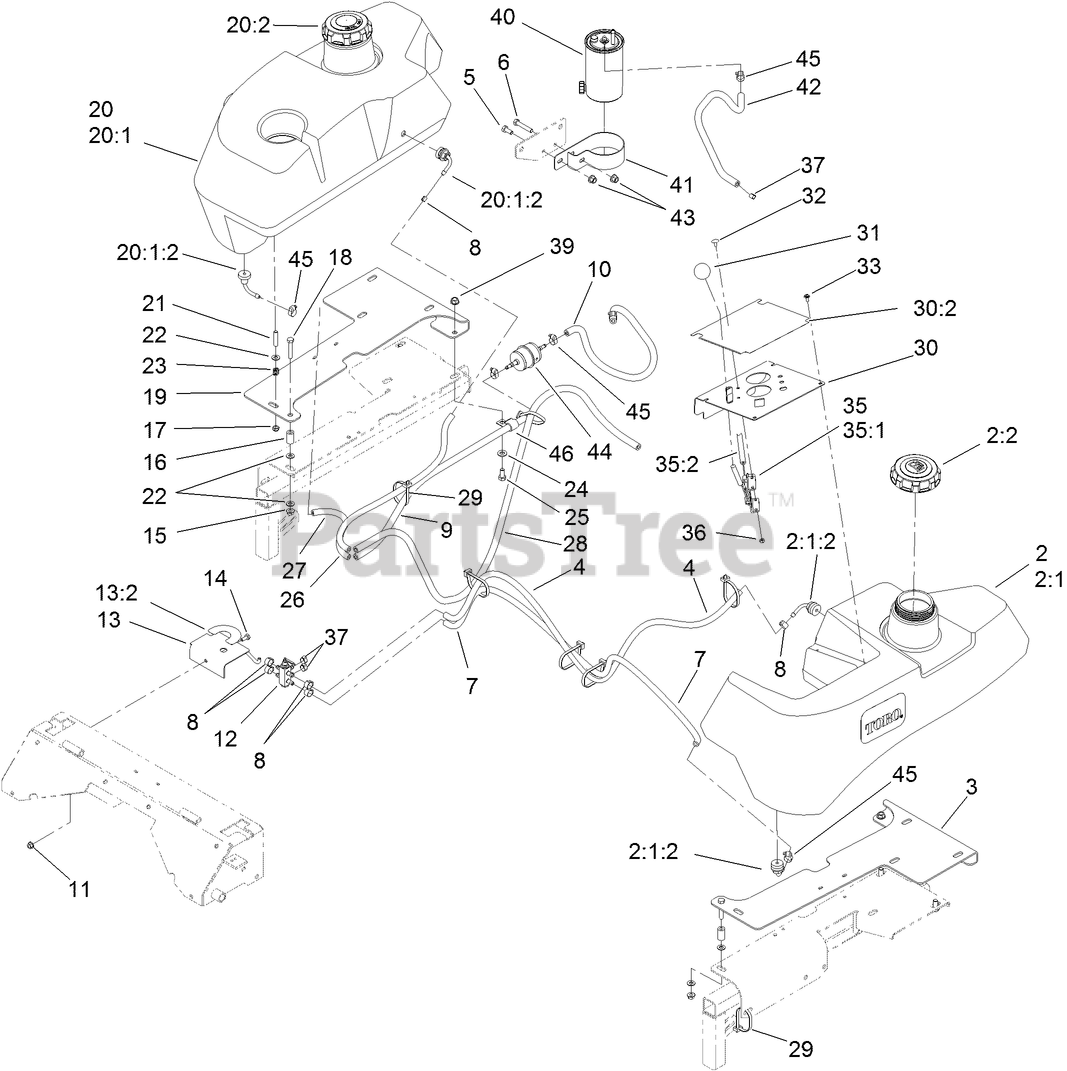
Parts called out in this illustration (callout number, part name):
2	LH FUEL TANK KIT
2:1	Tank-Fuel, LH
2:1:2	FITTING-FUEL, BULKHEAD
2:2	BIODIESEL CAP ASM
3	BRACKET-FUEL TANK, LH
4	HOSE-FUEL
5	SCREW-HH
6	SCREW-HH
7	HOSE-FUEL
8	CLAMP-HOSE, FUEL
9	HOSE-FUEL
10	HOSE-FUEL
11	NUT-HF
12	VALVE-FUEL, DUAL FLOW
13	BRACKET-VALVE, FUEL
13:2	DECAL-VALVE, FUEL
14	SCREW-HH
15	NUT-LOCK, NI
16	SPACER
17	NUT-LOCK, NI
18	SCREW-HH
19	BRACKET-FUEL TANK, RH
20	RH FUEL TANK KIT
20:1	Tank-Fuel, RH
20:1:2	FITTING-FUEL, BULKHEAD
20:2	BIODIESEL CAP ASM
22	WASHER-PLAIN
23	SPRING-TANK, FUEL
24	WASHER-FLAT
25	SCREW-HH
26	HOSE-FUEL
27	HOSE-FUEL
28	HOSE-FUEL
29	TIE-PLASTIC
30	CONTROL PANEL ASM
30:2	DECAL - PANEL, CONTROL
31	KNOB-BALL
32	BOLT-CARR
33	SCREW-PPH
35	THROTTLE CONTROL CABLE ASM
35:1	LEVER-THROTTLE
36	NUT-LOCK, NI
37	CLAMP-HOSE, FUEL
39	NUT-HHF, WHIZ
40	ELEMENT-FILTER, FUEL/WATER
41	BRACKET-FILTER, FUEL
42	HOSE-FUEL
43	NUT-LOCK, NI
44	FILTER-INLINE
45	CLAMP-WORM
46	CLAMP-J
